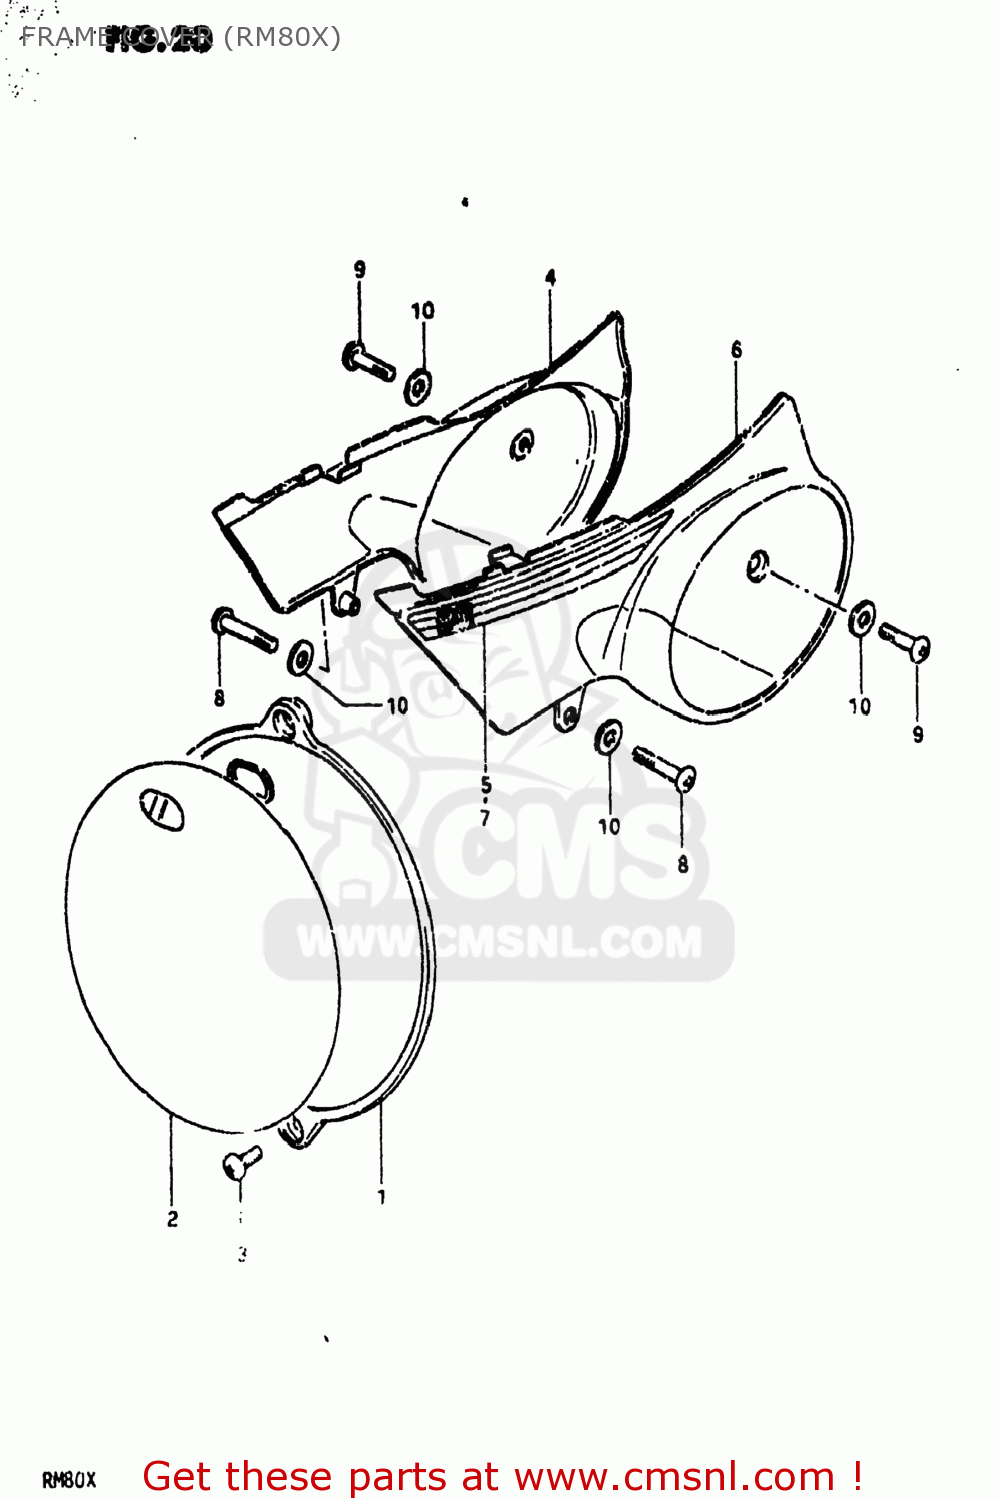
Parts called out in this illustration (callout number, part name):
1	PLATE,NUMBER,FRONT
2	EMBLEM,FRONT NUMBER PLATE
3	SCREW
4	COVER,FRAME,R(YELLOW)
5	TAPE,FRAME COVER
6	COVER,FRAME,LEFT
7	TAPE,FRAME COVER
8	SCREW, NO. 1
9	SCREW
10	WASHER
